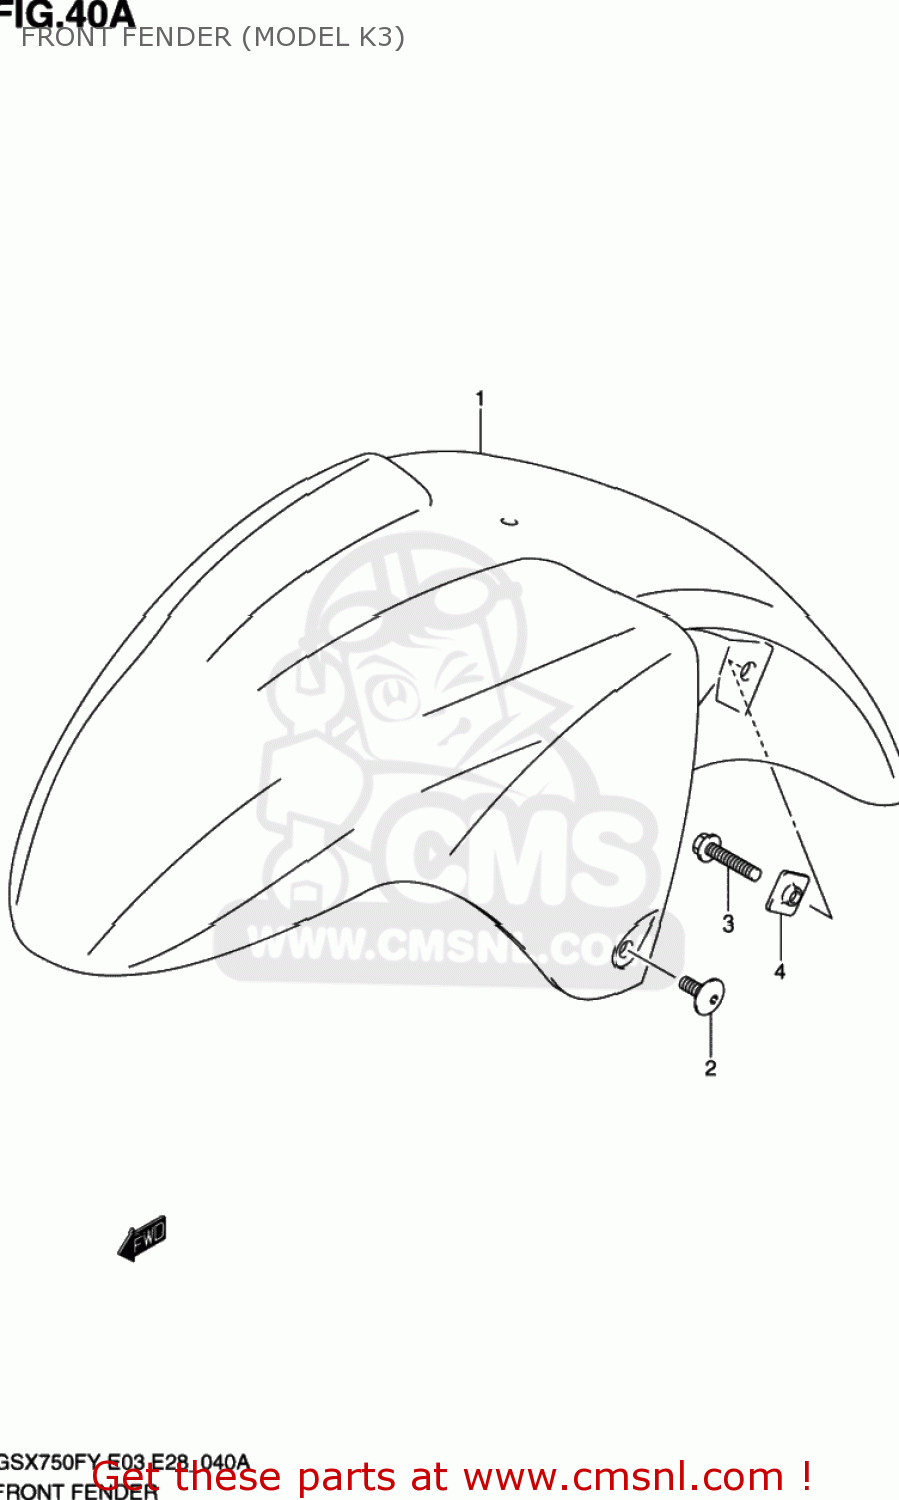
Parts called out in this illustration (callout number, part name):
1	FENDER,FR
2	SCREW(6X16)
3	BOLT
4	NUT,FR FENDER
